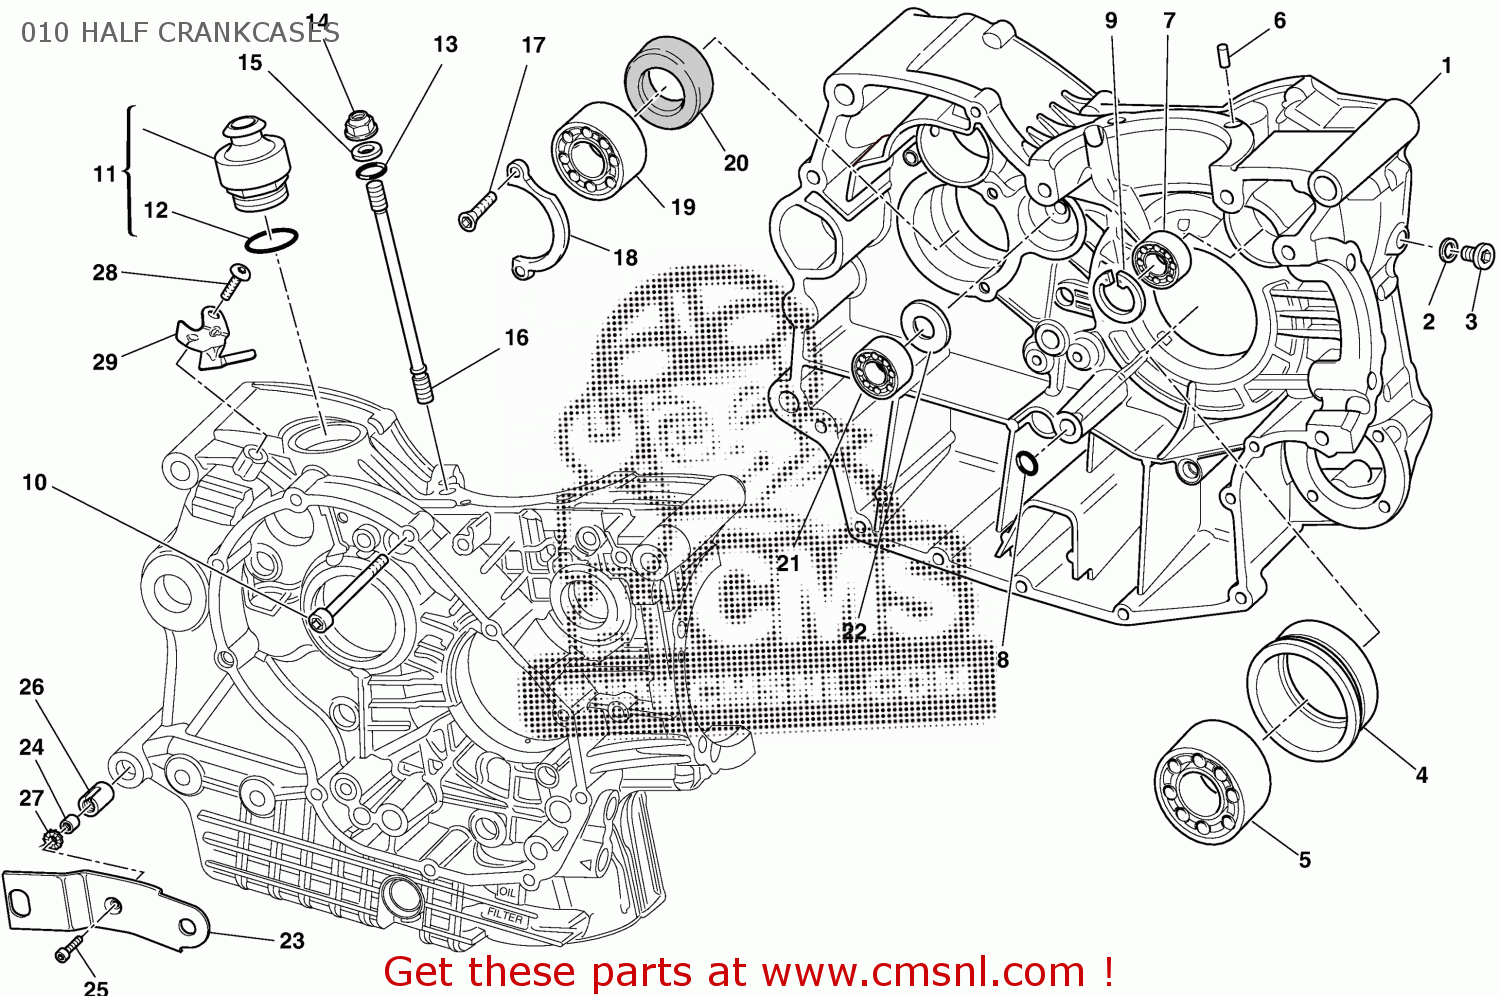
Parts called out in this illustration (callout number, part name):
1	CRANKCASE
2	GASKET, ALUMINIUM 12X16X1.5
3	SCREW M12X1
4	BUSHING
5	BEARING
6	PIN DOWEL
7	BALL BEARING 6003 TN9 C3
8	O-RING
9	CIRCLIP
10	SCREW TCEI M8X75
11	VALVE, BREATHER
12	O RING 39.34X2.62
13	O RING 2031
14	NUT
15	WASHER, SPECIAL 10.5X21X2
16	STUD BOLT, CYLINDER HEAD
17	SCREW TSPEI M6X12
18	PLATE, RETAINER
19	BEARING
20	OIL SEAL
21	BEARING 17X40X12
22	WASHER
23	RIGHT BRACKET
24	BUSH, CONICAL
25	SCREW TCEIF M6X25
26	SPINDLE, TAPER
27	TOOTHED LOCK WASHER
28	SCREW TBEI M8X10
29	HOLDER SENSOR
